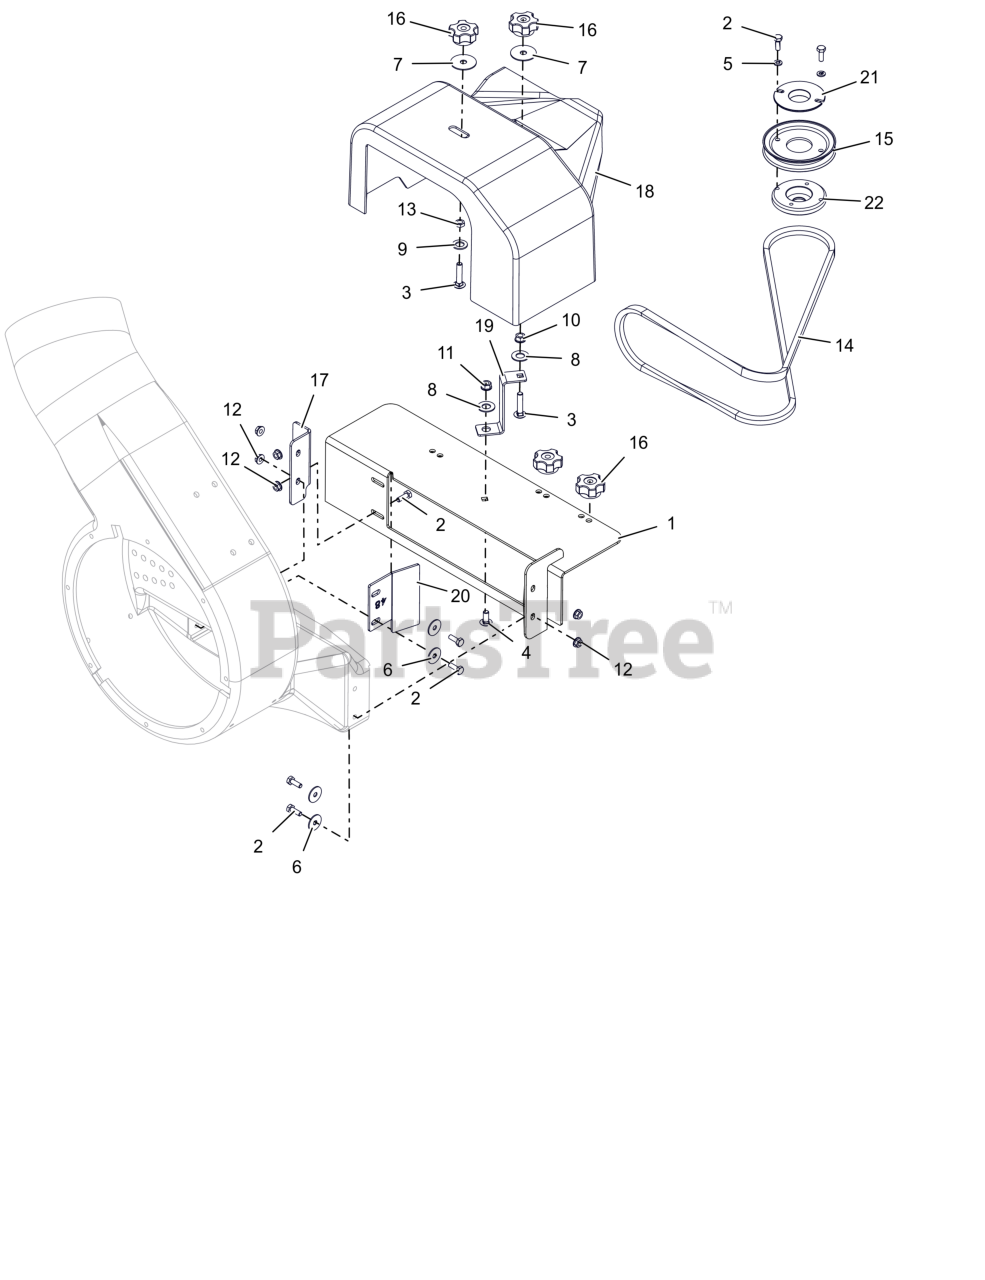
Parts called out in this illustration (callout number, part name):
1	WLDMT- BLOWER MTG
2	BLT, HEX .25-20X.75 G5 ZCC
3	BLT,RHSN .31-18X1.50 G5 ZCC
4	BLT, RHSSN.31-18X.750 G5 ZCC
5	WSHR,LK-REG .250X.062 ZCC
6	WSHR,FLT .281X1.000X.063 ZCC
7	WSHR,FLT .380X1.50X.062 ZCC
8	WSHR, FLT .505X1.00X.062 ZCC
9	WSHR, FLT .505X.880X.072 ZCC
10	NUT,SPNLK-FLG .31-18 G5 ZCC
11	NUT,LK-CTR-FLG .31-18 GF ZCC
12	NUT-LK-TOP-FLG .250-20 GF ZCC
13	NUT-JAM .312-18 G2 ZCC
14	V-BELT, 48"
15	PULLEY-V-4.25 ODX1.51 ID ZC120
16	KNOB-CLAMPING, .312-18 NYLOC
17	BRKT- BLOWER REAR MTG BLK
18	GUARD, 48" BLOWER BELT
19	BRKT, BLOWER GUARD MTG
20	BRKT- 48" BLOWER CLOSE-OFF
21	ADAPTER- BAGGER SHEAVE
22	ADAPTER- PULLEY IKON
